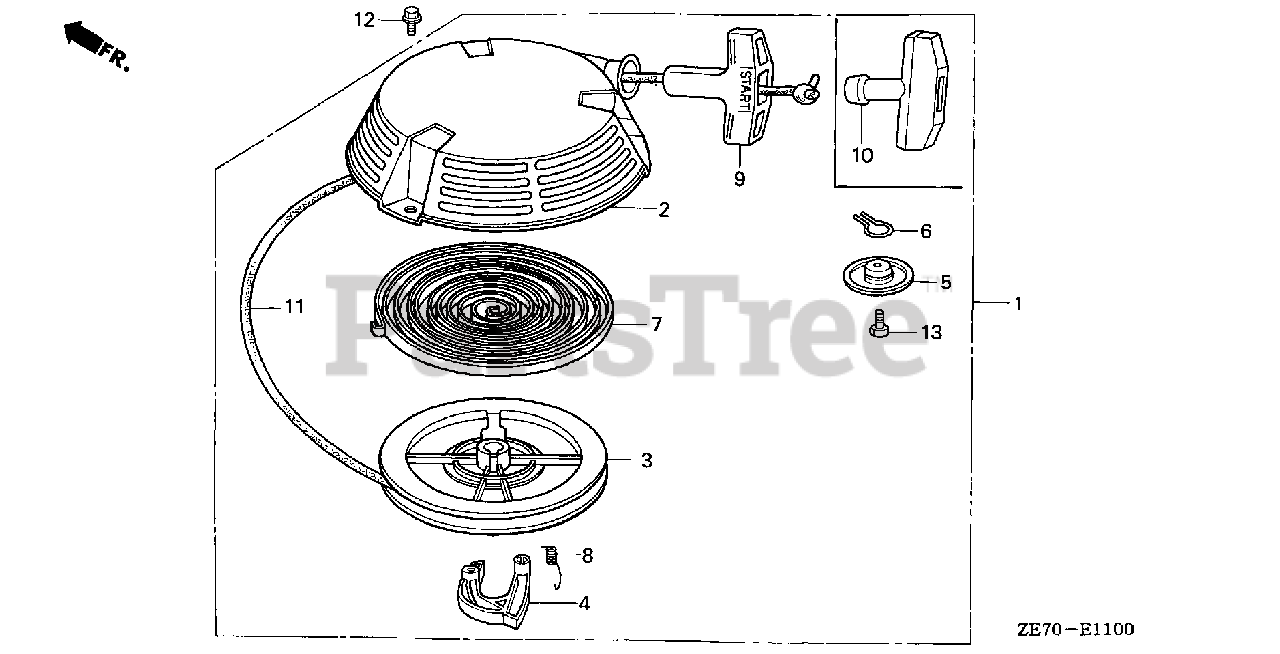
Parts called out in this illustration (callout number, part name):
1	STARTER ASSY., RECOIL *R8* (BRIGHT RED)
1	STARTER ASSY., RECOIL *R280* (POWER RED)
2	CASE, RECOIL STARTER *R8* (BRIGHT RED)
3	PULLEY, RECOIL STARTER
4	RATCHET, STARTER
5	PLATE, FRICTION
6	SPRING, FRICTION
7	SPRING, RECOIL STARTER
8	SPRING, RETURN
9	KNOB, RECOIL STARTER
11	ROPE, RECOIL STARTER
11	ROPE (#4X55")
12	BOLT, FLANGE (6X8)
13	BOLT, HEX. (6X12)
